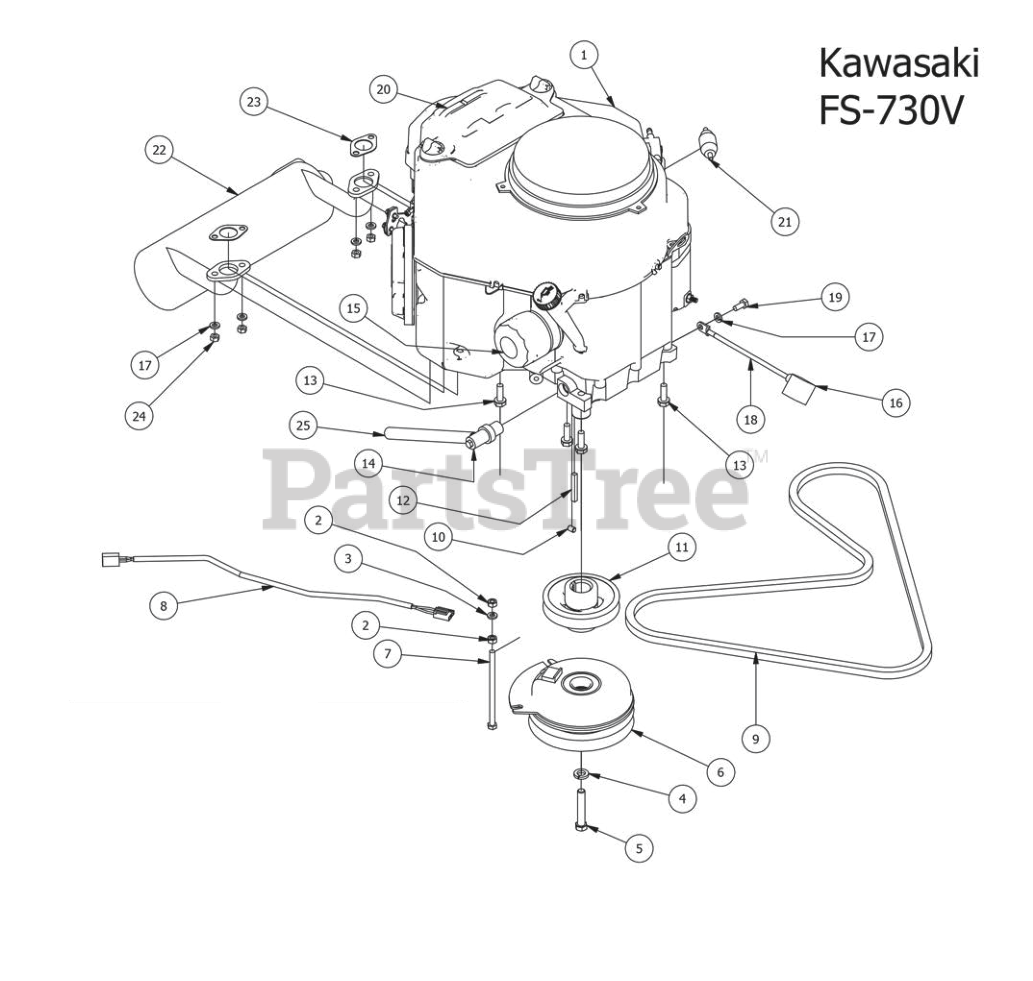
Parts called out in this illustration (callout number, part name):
1	FS730V Engine
3	5/16" Lock Washer
4	7/16" Lock Washer
5	7/16" x 2 1/2" Hex Bolt
6	Clutch Assembly
7	5/16-18 x 5-1/2 GR 5 Hex Bolt
8	Clutch Pigtail
10	5/16 Set Screw
11	4 3/4 Motor Pulley
12	1/4 x 2 Square key Stock
13	3/8 x 1 1/8 bolt
15	Oil Filter
16	Black Boot For ground cable
17	5/16" Lock Washer
18	Ground Cable
19	M8x1.20x20MM Hex head bolt
20	Kaw air Filter For Engine
21	Universal inline Fuel Filter
22	Exhaust-Stand On (kawasaki engine)
23	Exhaust gasket
24	M8-1.25 Zinc Nut
25	1/2 Clear Braded Hose Priced/Foot
